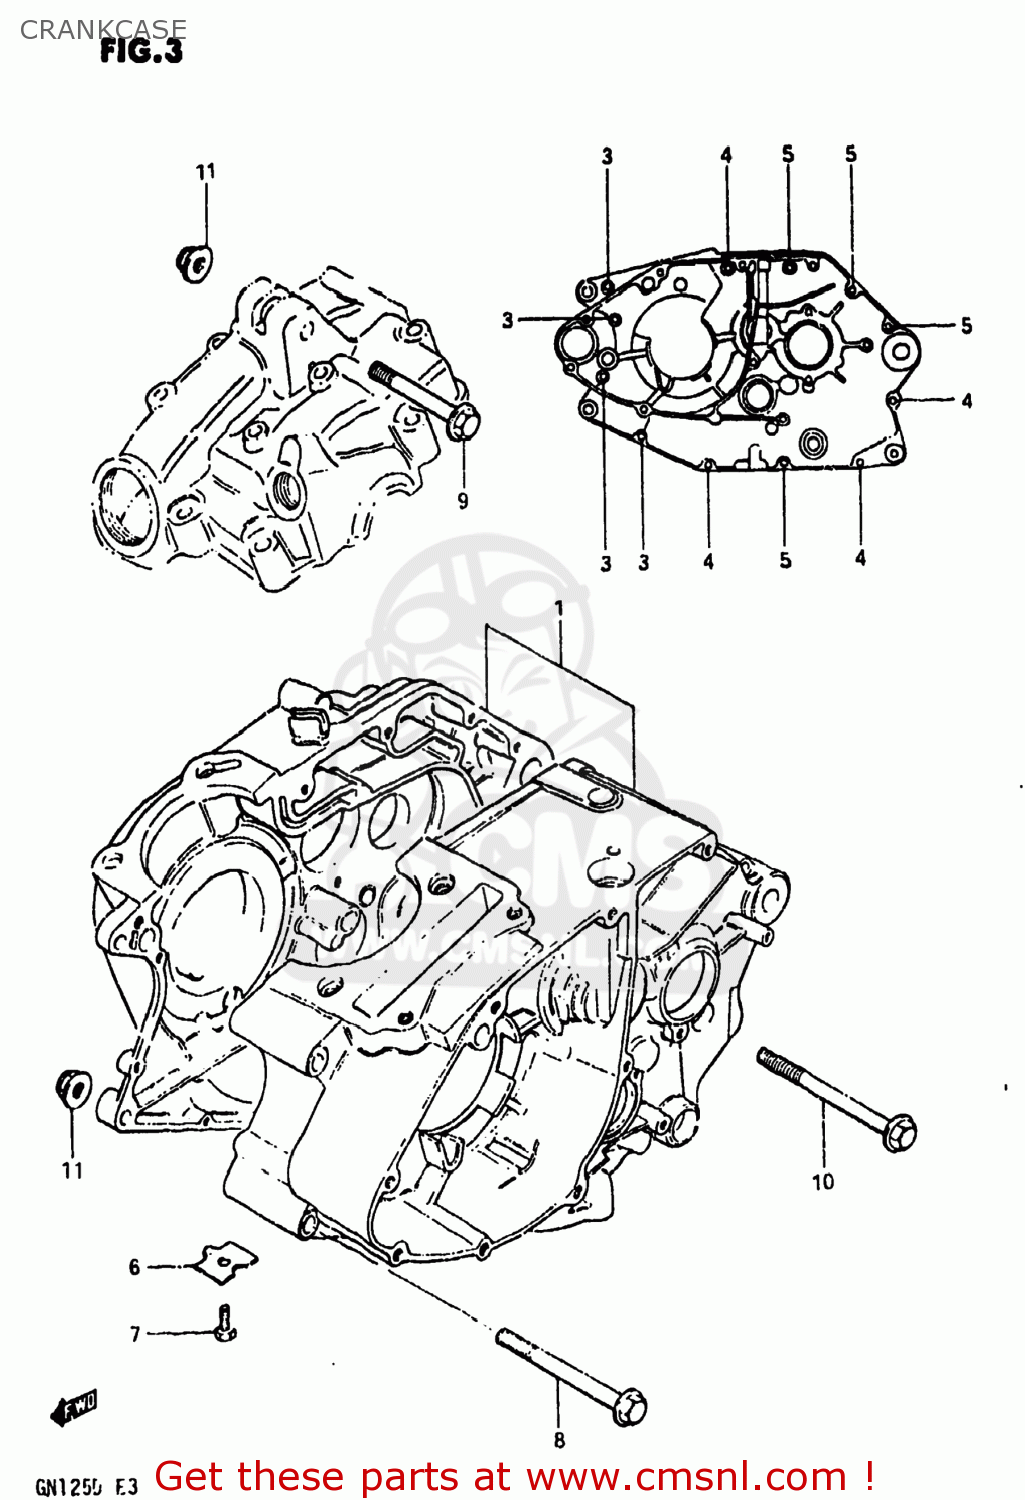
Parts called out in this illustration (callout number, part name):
1	CRANKCASE SET
2	PIN
3	BOLT (6X55)
4	BOLT
5	BOLT
6	PLATE,OIL GALLERY PLUG
7	BOLT
8	BOLT(8X80)
9	BOLT(8X50)
10	BOLT(8X88)
11	NUT
